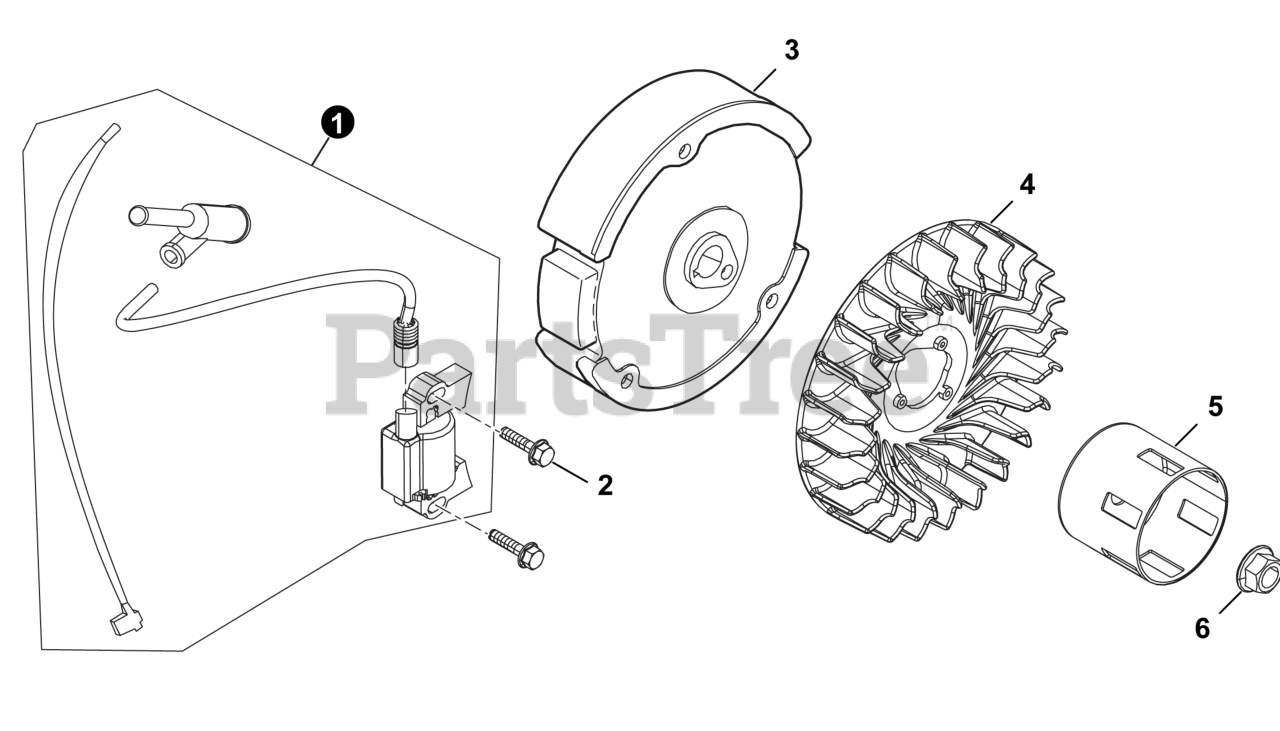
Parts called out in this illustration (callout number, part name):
1	COIL, IGNITION
3	FLYWHEEL
4	IMPELLER
5	STARTER ASSY., RECOIL
6	NUT, FLYWHEEL
